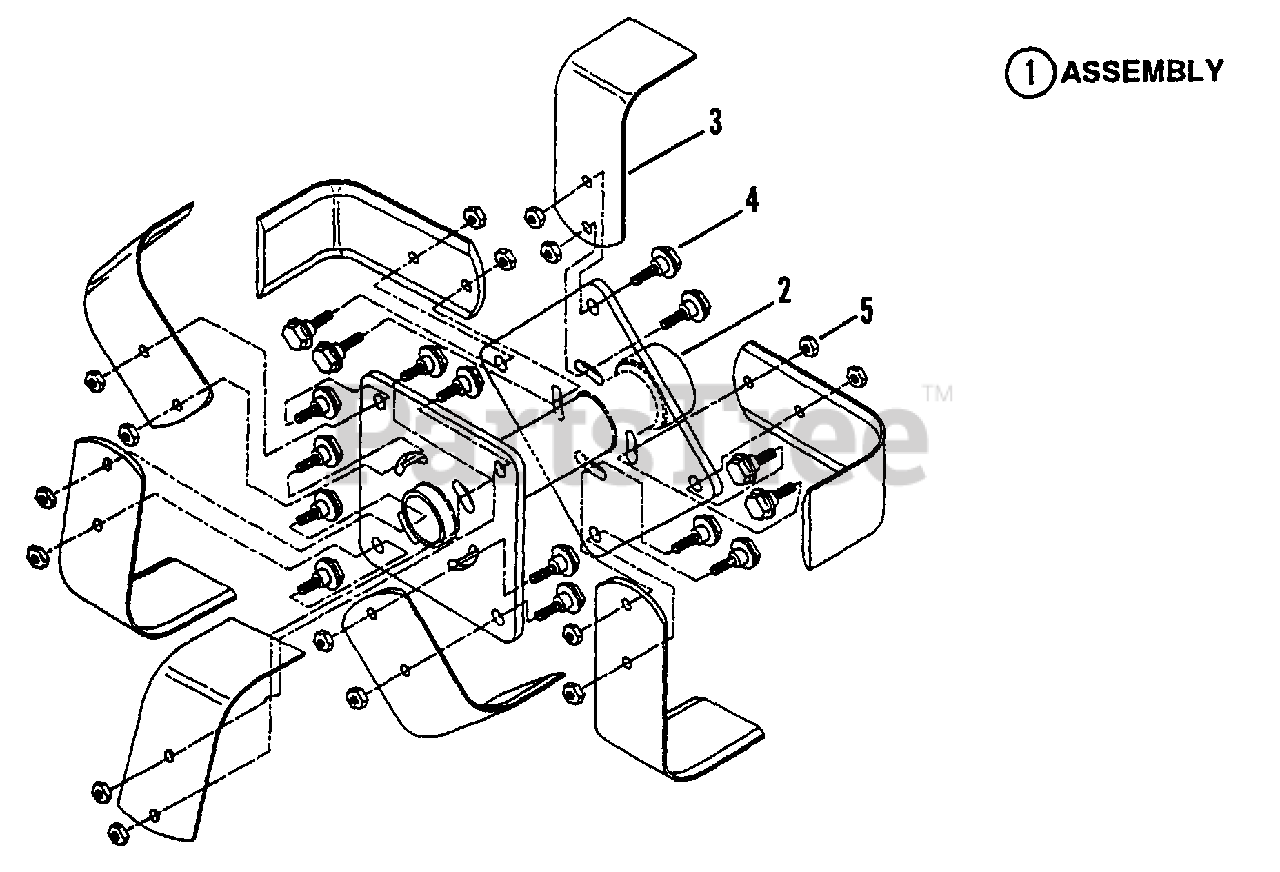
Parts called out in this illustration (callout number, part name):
1	(NLA) ASSEMBLY, RT8 (8HP)(Includes items 1 thru 5, order individual parts)
1	(NLA) ASSEMBLY, Tine (5HP)(Includes items 1 thru 5, order individual parts)
2	STRUCTURE, Tine Hub
3	TINE, 13" (8HP)
3	TINE, 11.5" (5HP)
4	BOLT, 3/8-24 Hex Flange Head (Shoulder)
5	NUT, 3/8-24 Hex Lock Gr 8
